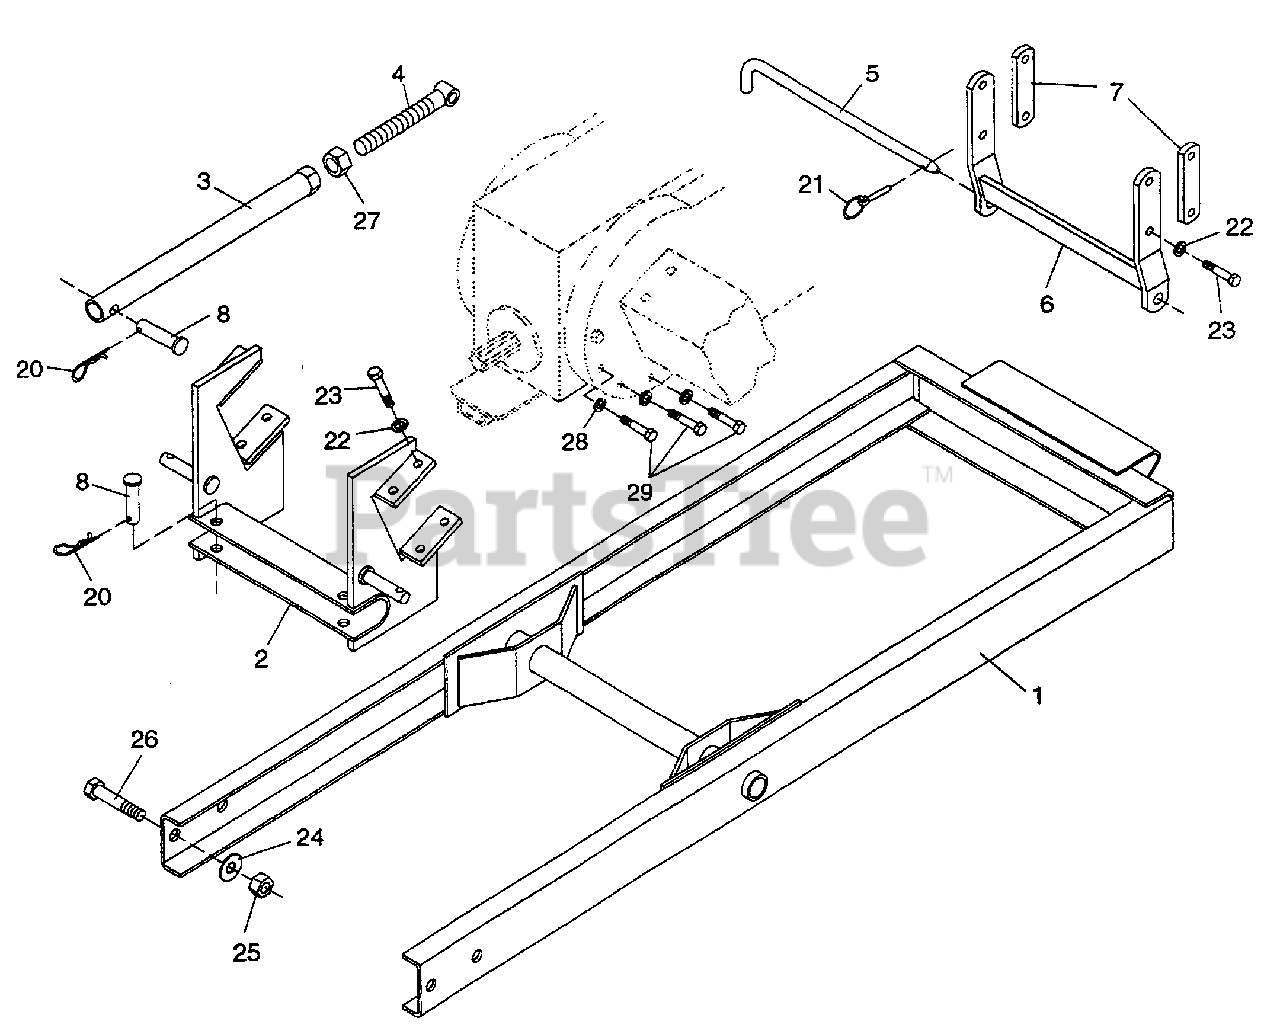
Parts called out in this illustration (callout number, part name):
1	Backhoe sub-frame 24.4 x 74 assembly
2	Rear mounting bracket assembly
3	Outer link assembly, 19.5
4	Inner top link assembly
5	3/4 x 17.75 Lock pin
6	Front mounting bracket assembly
7	Link, .50 x 1.50 x 6.25
8	3/4 x 3-1/4 Clevis pin
20	1/8 Safety pin
21	1/4 x 1-3/4 Klik pin
22	9/16 Standard lockwasher
23	14mm x 2.0P x 35mm Hex head cap screw
24	7/8 Lockwasher
25	7/8 Hex nut
26	7/8 NC x 2-1/2 Hex head cap screw GR5
27	1" NC Hex nut
28	1/2 Lockwasher
29	12mm x 1.75P x 80mm Hex head cap screw
